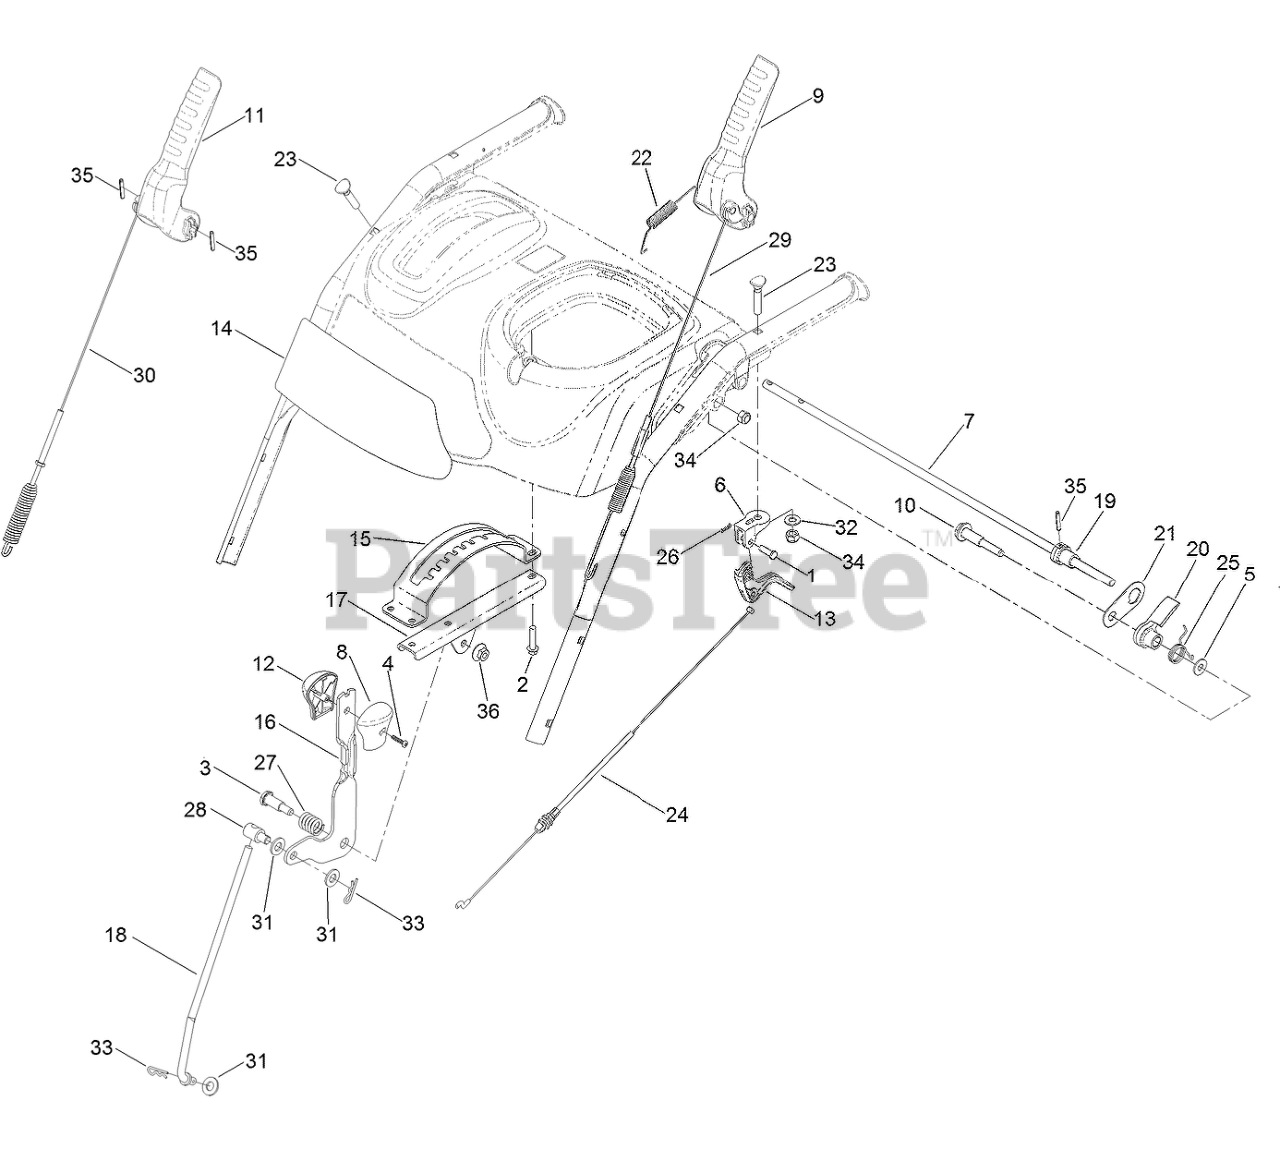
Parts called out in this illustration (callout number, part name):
1	PIN-CLEVIS
2	SCREW-PLASTITE
3	SCREW-SHOULDER
4	SCREW-PPH
5	WASHER-FLAT
6	MOUNT-CLUTCH, LEVER
7	ROD-LOCKOUT
8	KNOB-SHIFT, LH
9	LEVER-TRACTION
10	SCREW-SHOULDER
11	LEVER-AUGER
12	KNOB-SHIFT, RH
13	LEVER-CLUTCH
15	GUIDE-SELECTOR, SPEED
16	SELECTOR-SPEED
17	BRACKET-SELECTOR, SPEED
18	ROD-SHIFT
19	CAM-LOCKOUT
20	LATCH-LOCKOUT
21	LINK-LOCKOUT
22	SPRING-TENSION
23	SCREW-HANDLE
24	CABLE-CLUTCH
25	SPRING-TORSION
26	PIN-HAIR
27	SPRING-COMPRESSION
28	TRUNNION-ROD
29	CABLE-TRACTION
30	CABLE-AUGER
31	WASHER-FLAT
32	WASHER-FLAT
33	PIN-COTTER
34	NUT-LOCK, NI
35	PIN-SPRING
36	NUT-HF
